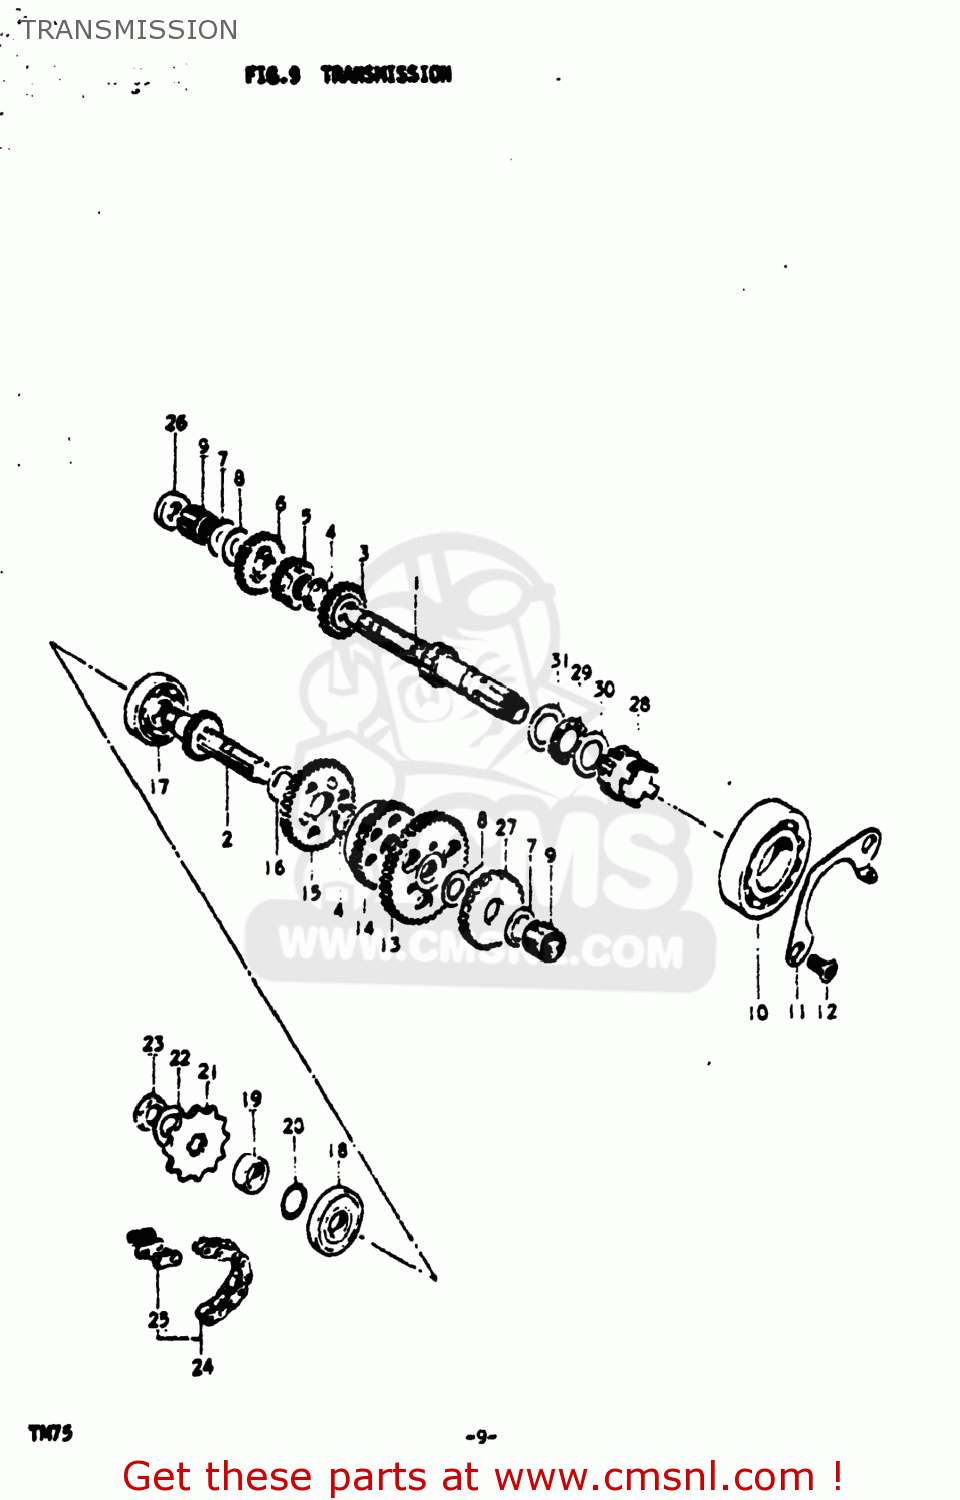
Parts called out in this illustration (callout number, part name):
1	SHAFT,COUNTER
2	SHAFT,DRIVE
3	GEAR,THIRD DRIVE
4	CIRCLIP
5	GEAR,SECOND DRIVE
6	GEAR,4TH DRIVE
7	WASHER(12X24X1.5)
8	WASHER
9	BEARING(12X19X12)
10	BEARING
11	PLATE,COUNTERSHAFT BEARING
12	SCREW
13	GEAR,FIRST DRIVEN
14	GEAR,3RD DRIVEN
15	GEAR,SECOND DRIVEN
16	WASHER
17	BEARING
18	SEAL,OIL(21X40X7)
19	SPACER(17X21X13)
20	O RING(D:1,ID:16.8)
21	SPROCKET(NT:15)
22	WASHER,LOCK
23	NUT
24	CHAIN ASSEMBLY,DRIVE
25	JOINT ASSEMBLY,CHAIN
26	SEAL,OIL(5.5X16X8)
27	GEAR,KICK STARTER IDLE
28	GEAR,KICK STARTER DRIVE
29	BEARING(20.1X35X2.8)
30	WASHER (20.1X29.5X0.8)
31	WASHER(20X34X0.8)
